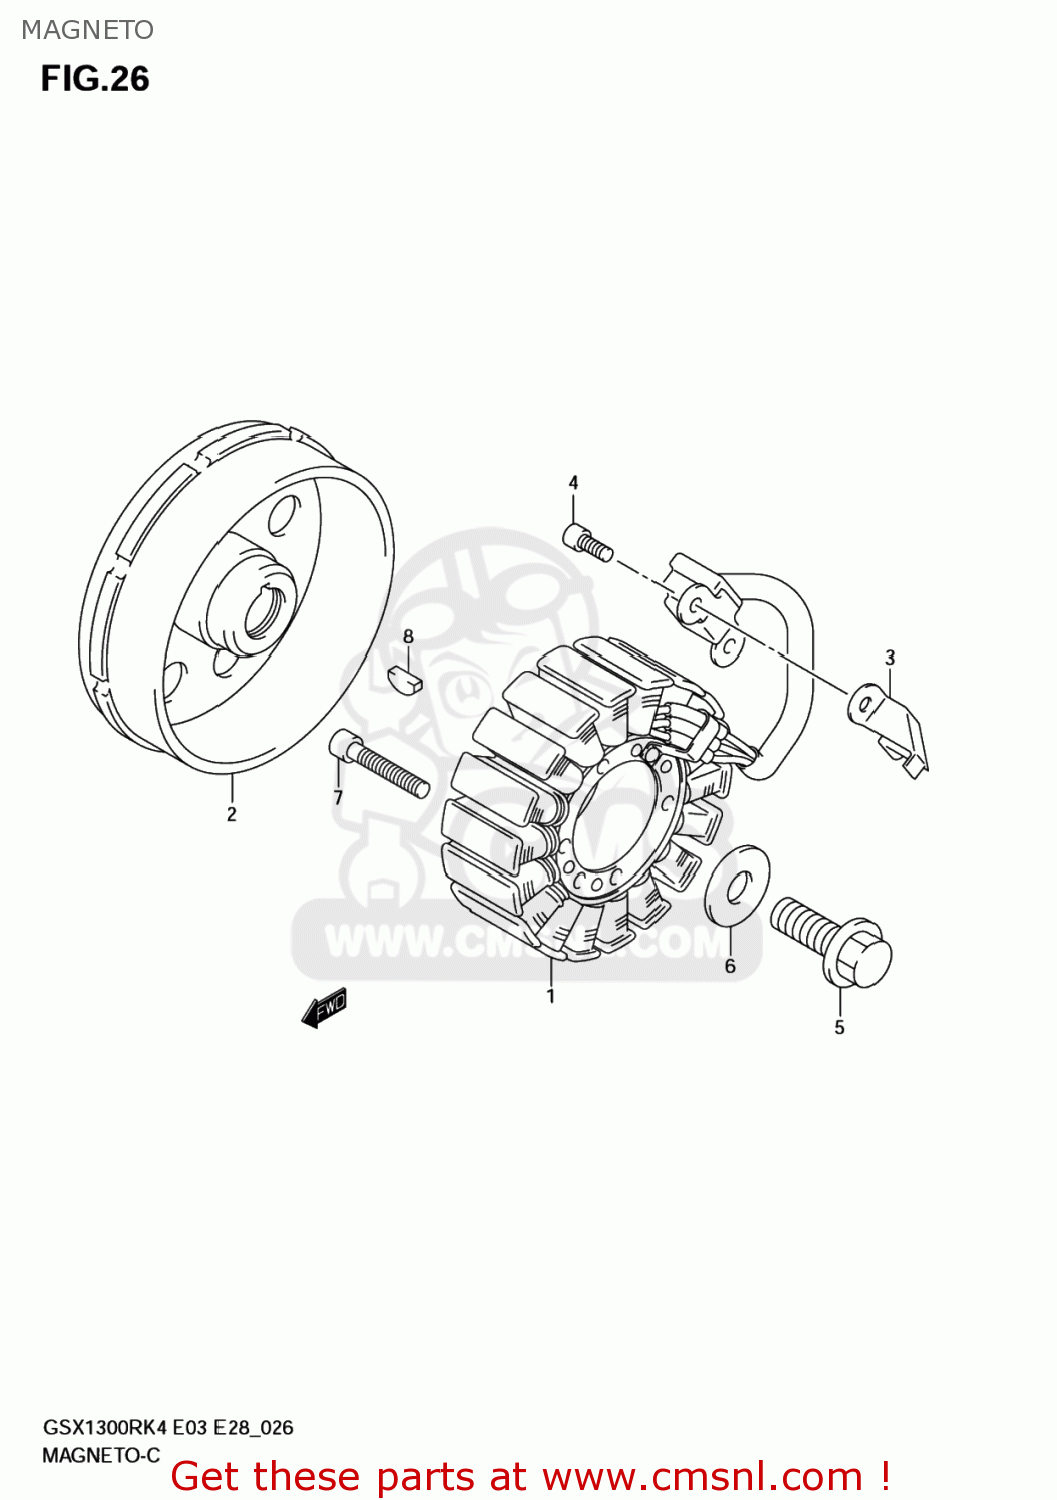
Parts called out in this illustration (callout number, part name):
1	STARTER ASSY
2	ROTOR ASSY
3	CLAMP,MAGNETO LEAD
4	BOLT
5	BOLT(12X30)
6	WASHER(12X30X3)
7	BOLT
8	KEY
